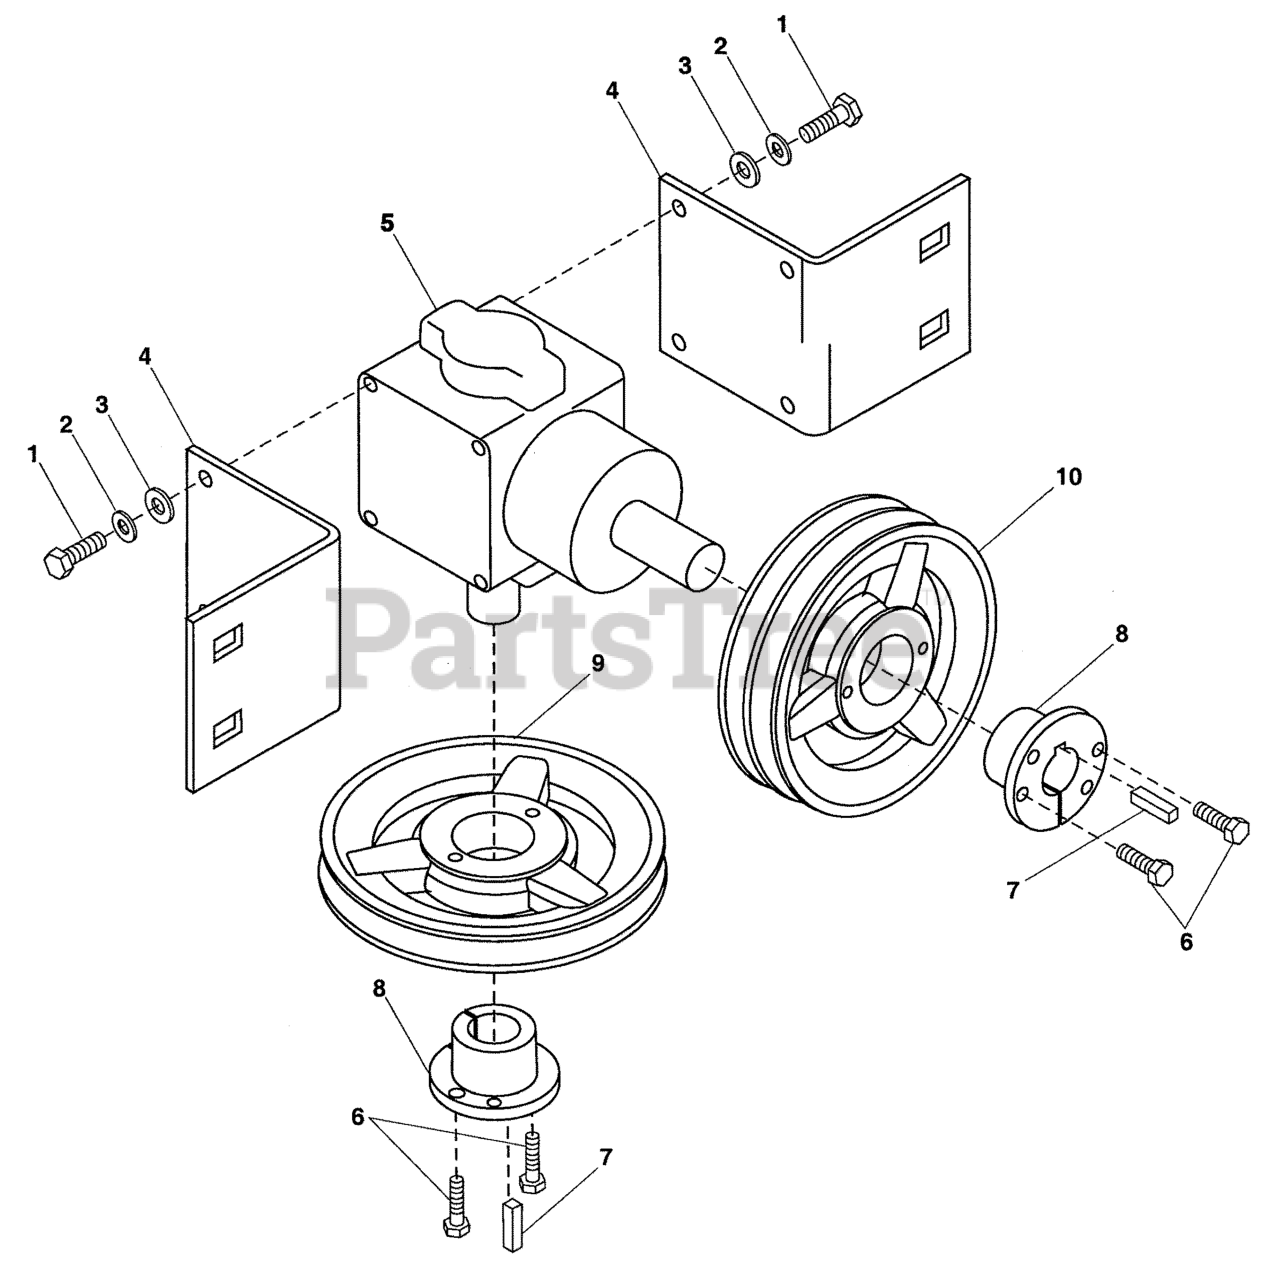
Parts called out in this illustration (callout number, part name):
1	BOLT, 5/16-18 X 1 GD5 YZ
2	WASHER, 5/16 LOCK CZ
3	WASHER, 5/16" SAE
4	GEAR BOX BRACKET
5	GEAR BOX
6	BOLT, 1/4-20 X 1" GD5 CZ
7	KEY, 1/4 x 2
8	TAPERED LOCK HUB
9	PULLEY, Spindle
10	PULLEY, Gear Box
